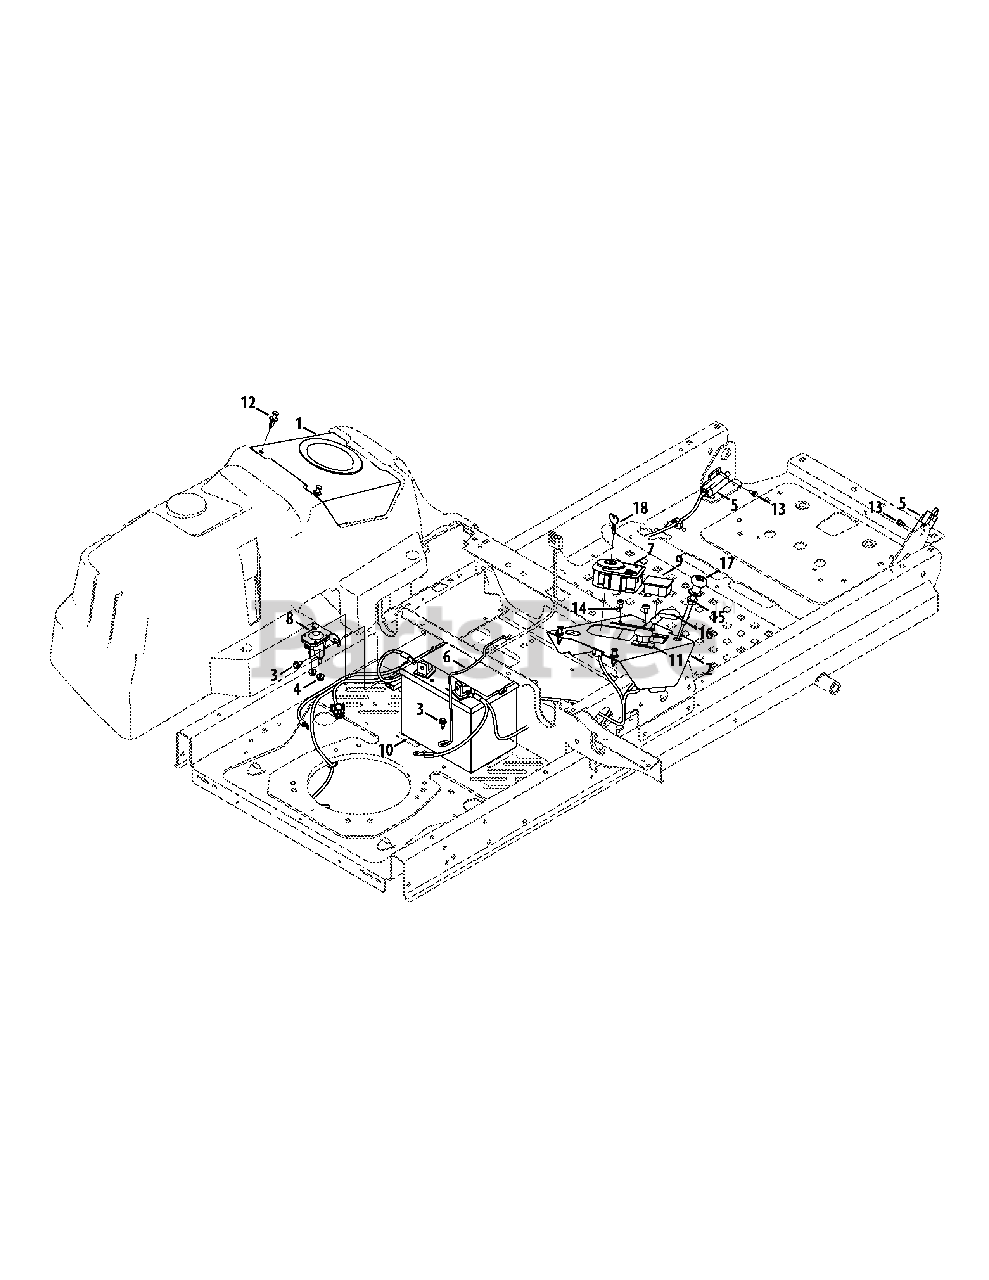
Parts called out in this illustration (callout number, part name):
1	Console Cover, LH
2	Console Cover, RH
3	Hex Washer Screw, 1/4-20 x .625
4	Flange Lock Nut, 1/4-20
5	Interlock Switch
7	Key Switch
8	Solenoid
9	Hour Meter/Service Minder
11	Electric PTO Switch
12	Plastic Rivet
13	Shoulder Screw, #10-32 x .500
14	Screw, 1/4-20 x .50
15	Flange Lock Nut, 3/8-16
16	Throttle Cable
17	Choke Cable
18	Key, Assembly
